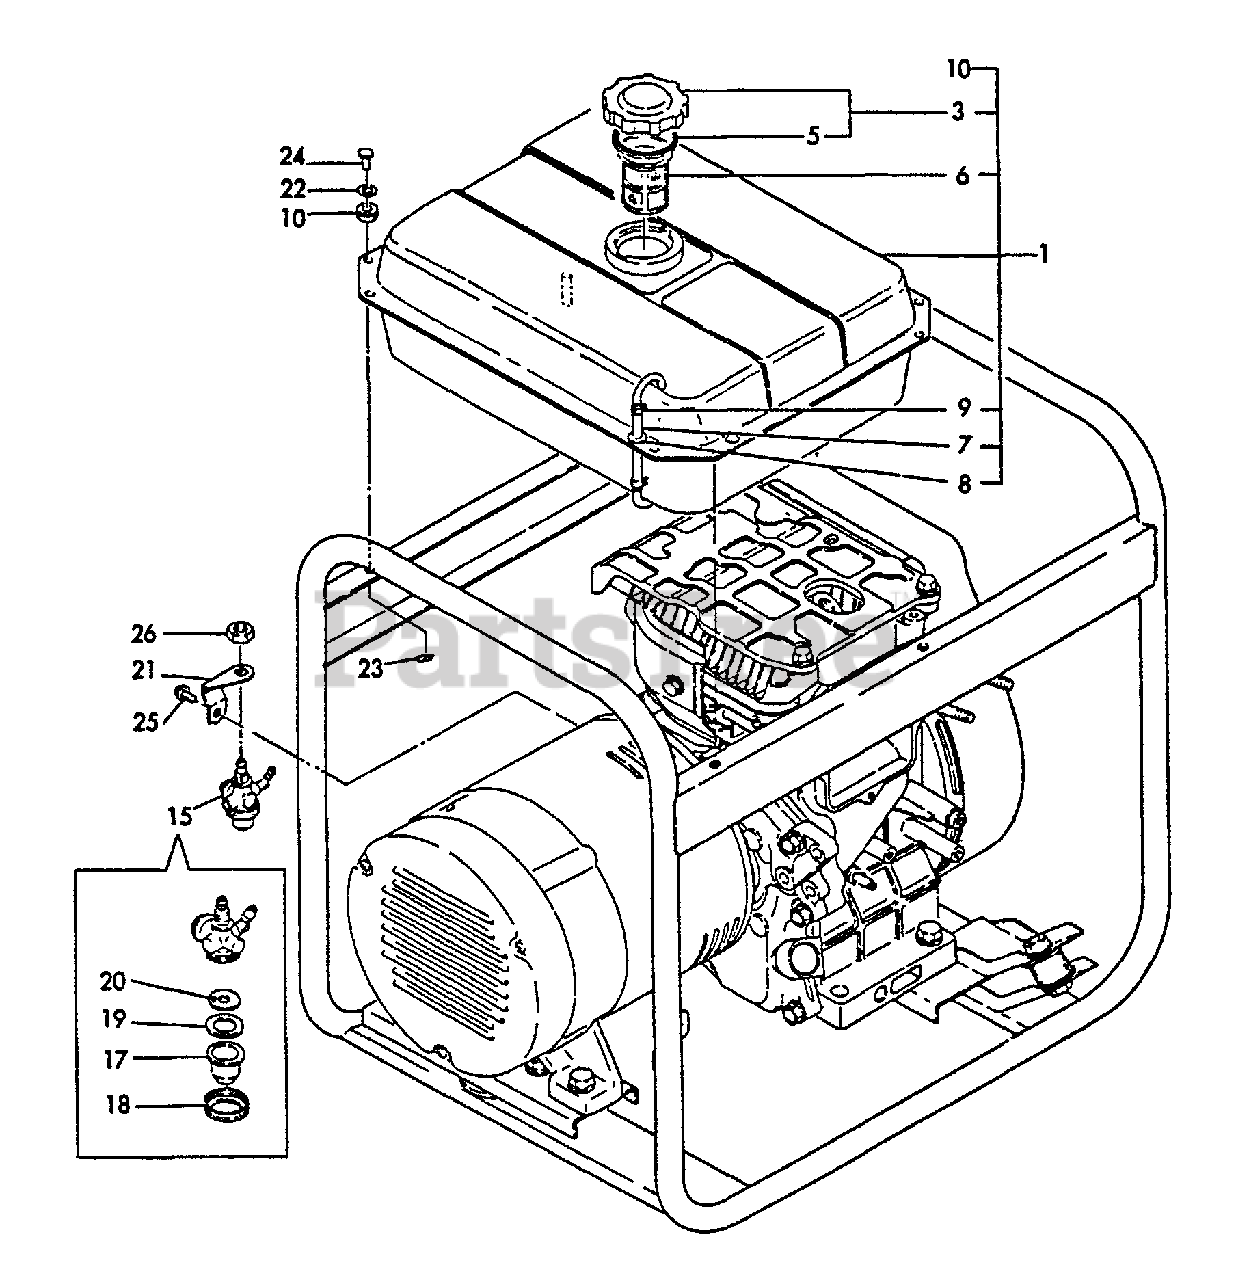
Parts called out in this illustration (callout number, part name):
1	FUEL TANK ASSY
3	CAP ASSY
5	GASKET
6	STRAINER, FUEL
7	PIPE, GAUGE
8	GROMMET
9	CLAMP, HOSE - 9
10	GROMMET
15	FUEL COCK ASSY
17	BOWL, STRAINER
18	RETAINER
19	GASKET
20	FILTER, FUEL
21	STAY, COCK
22	WASHER
23	PIN - 6 -- SNAP
24	PIN - 6X14
25	BOLT - 8X14 -- PLATED
26	LOCKNUT - 12
